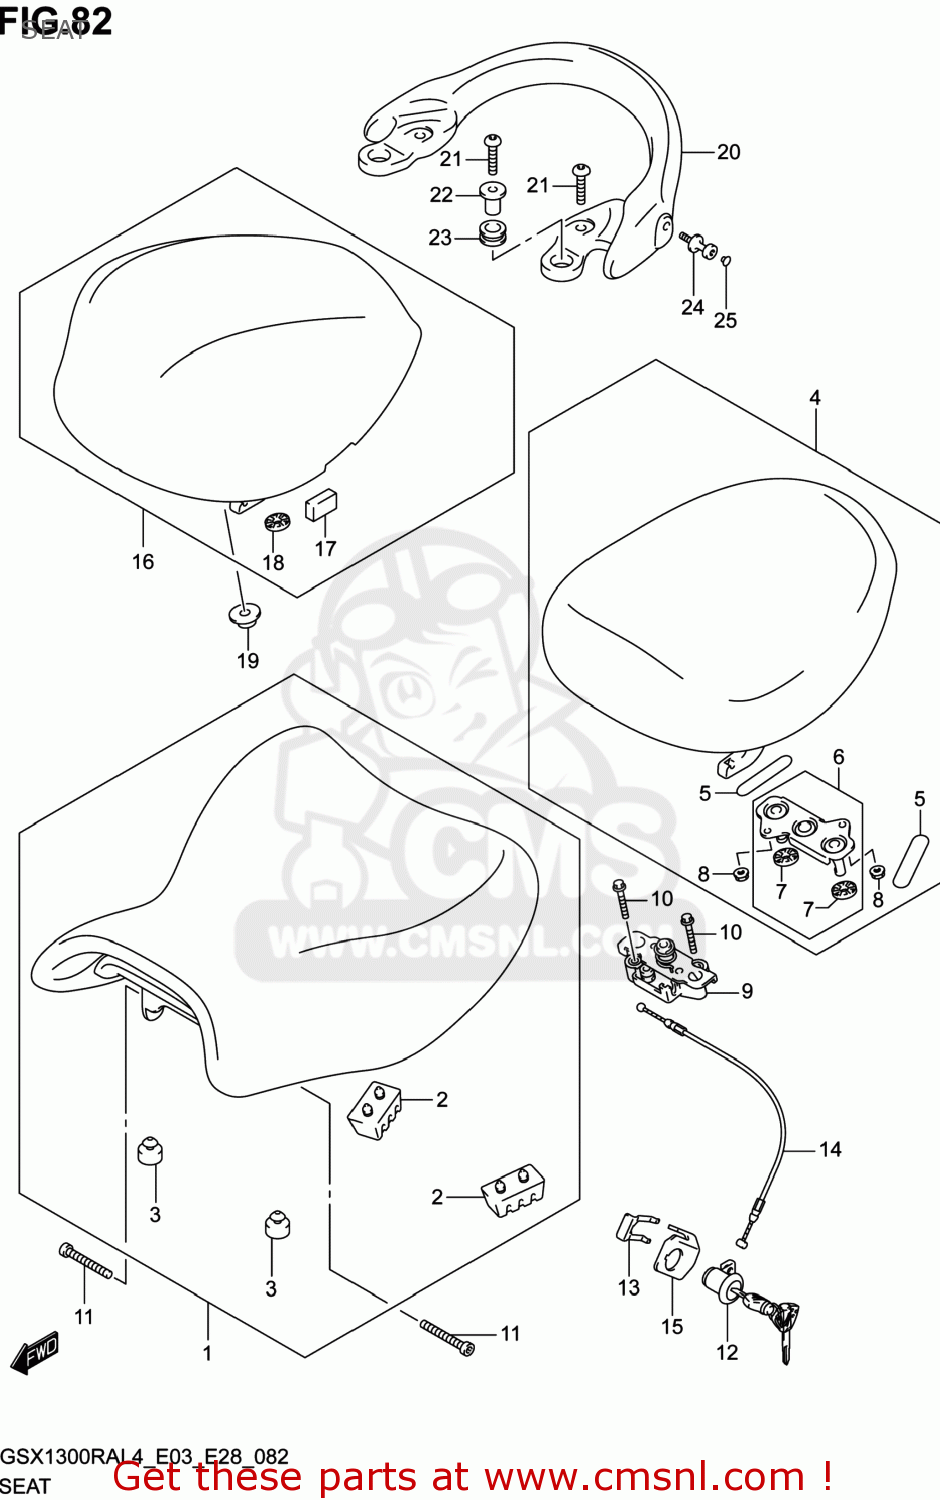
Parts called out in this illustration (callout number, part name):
1	SEAT ASSY
2	CUSHION,SUPPORT(50X25X32)
3	CUSHION
4	SEAT ASSY,PILLI
5	CUSHION
6	STRIKER,SEAT LOCK
7	CUSHION
8	NUT
9	BRACKET,STRIKER SUPPORT
10	BOLT
11	BOLT,SEAT FR
12	LOCK SET,SEAT
13	PLATE,SEAT LOCK ASSY
14	CABLE,SEAT LOCK
15	GUIDE,SEAT LOCK CABLE
16	BOX,SEAT TAIL(RED)
17	CUSHION
18	CUSHION
19	WASHER,FRAME COVER
20	HANDLE,PILLION RIDER
21	BOLT(8X33)
22	WASHER,PILLION
23	CUSHION,PILLION RIDER HANDLE
24	HOOK,PILLION RIDER HANDLE
25	CAP(OD:10)
